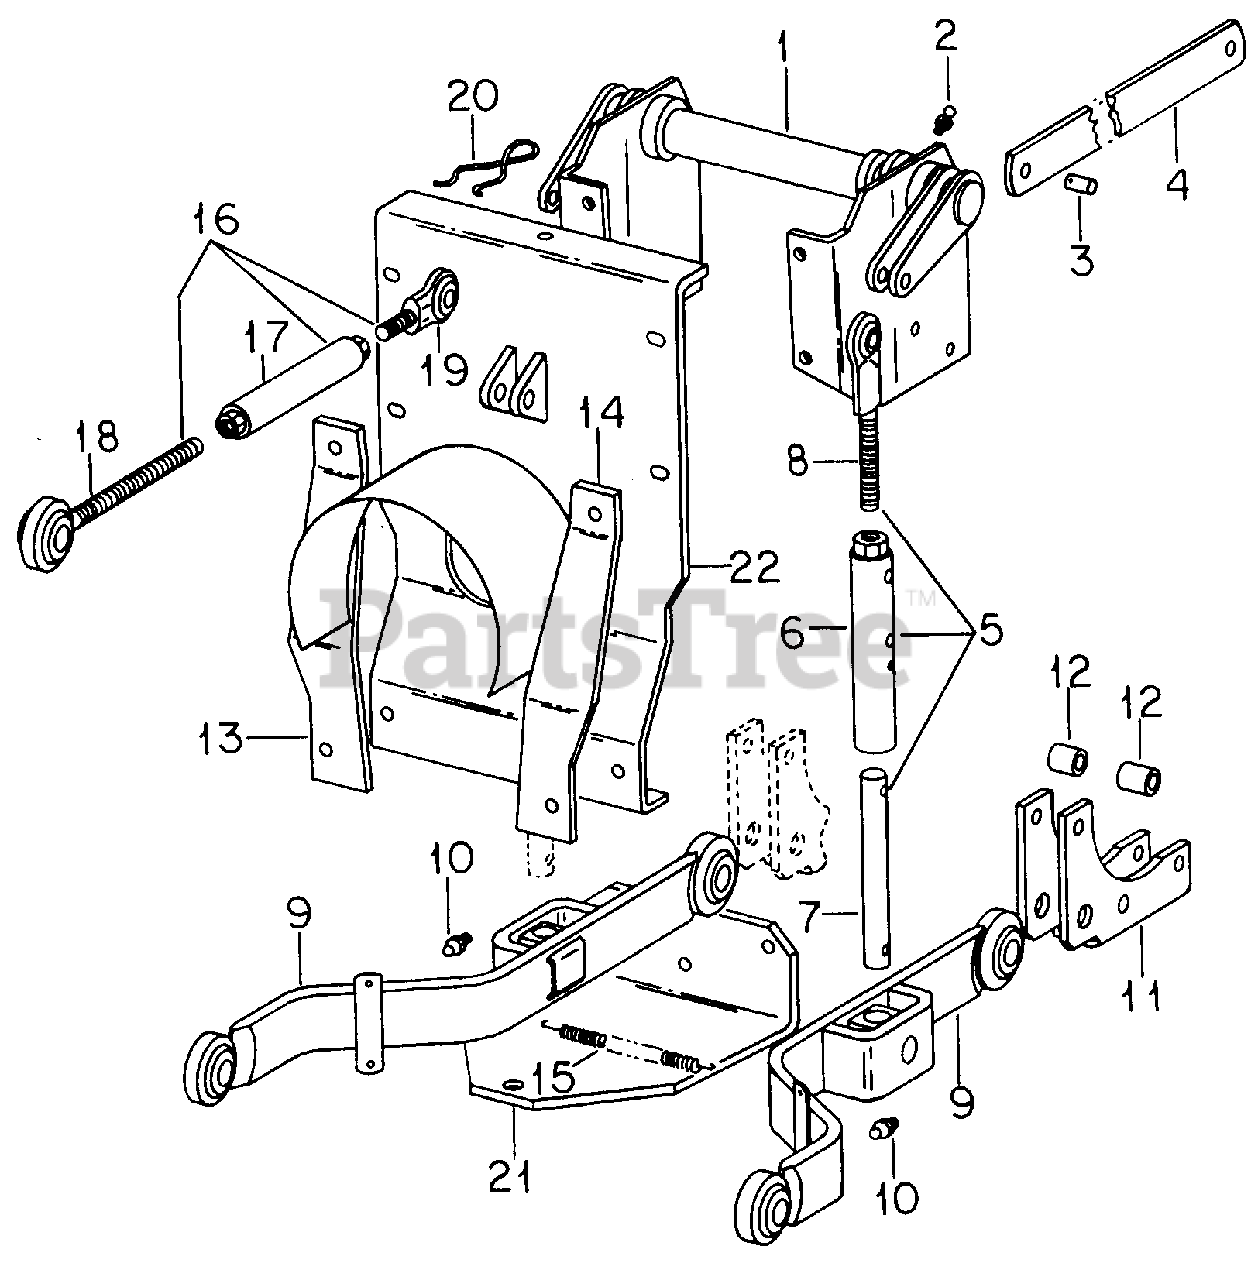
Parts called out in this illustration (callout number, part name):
1	Rockshaft Assy
2	Fitting, Straight Dr Type Lub
3	Pin, Bell Crank Clevis
4	Bar, Implement Lift
5	Link Assy, Lift
6	Tube Assy, Lift Link
7	Stud, Lift Link
8	Rod & End Assy, Lift Link
9	Link Assy, Lower
10	Fitting, 1/4-28 Taper Dr Thd 90 Degree Elbow Lub
11	Plate, Lower Link Support
12	Spacer, Plate Lower Link Support
13	Cam, Sway Limiter, LH
14	Cam, Sway Limiter, RH
15	Spring, Sway Limiter
16	Link Assy, Upper
17	Tube Assy, Upper Link
18	Rod Assy, Upper Link Rear
19	Rod Assy, Upper Link
20	Bail, Upper Link Storage
21	Bar, Drawbar
22	Plate Assy, Drawbar Support
